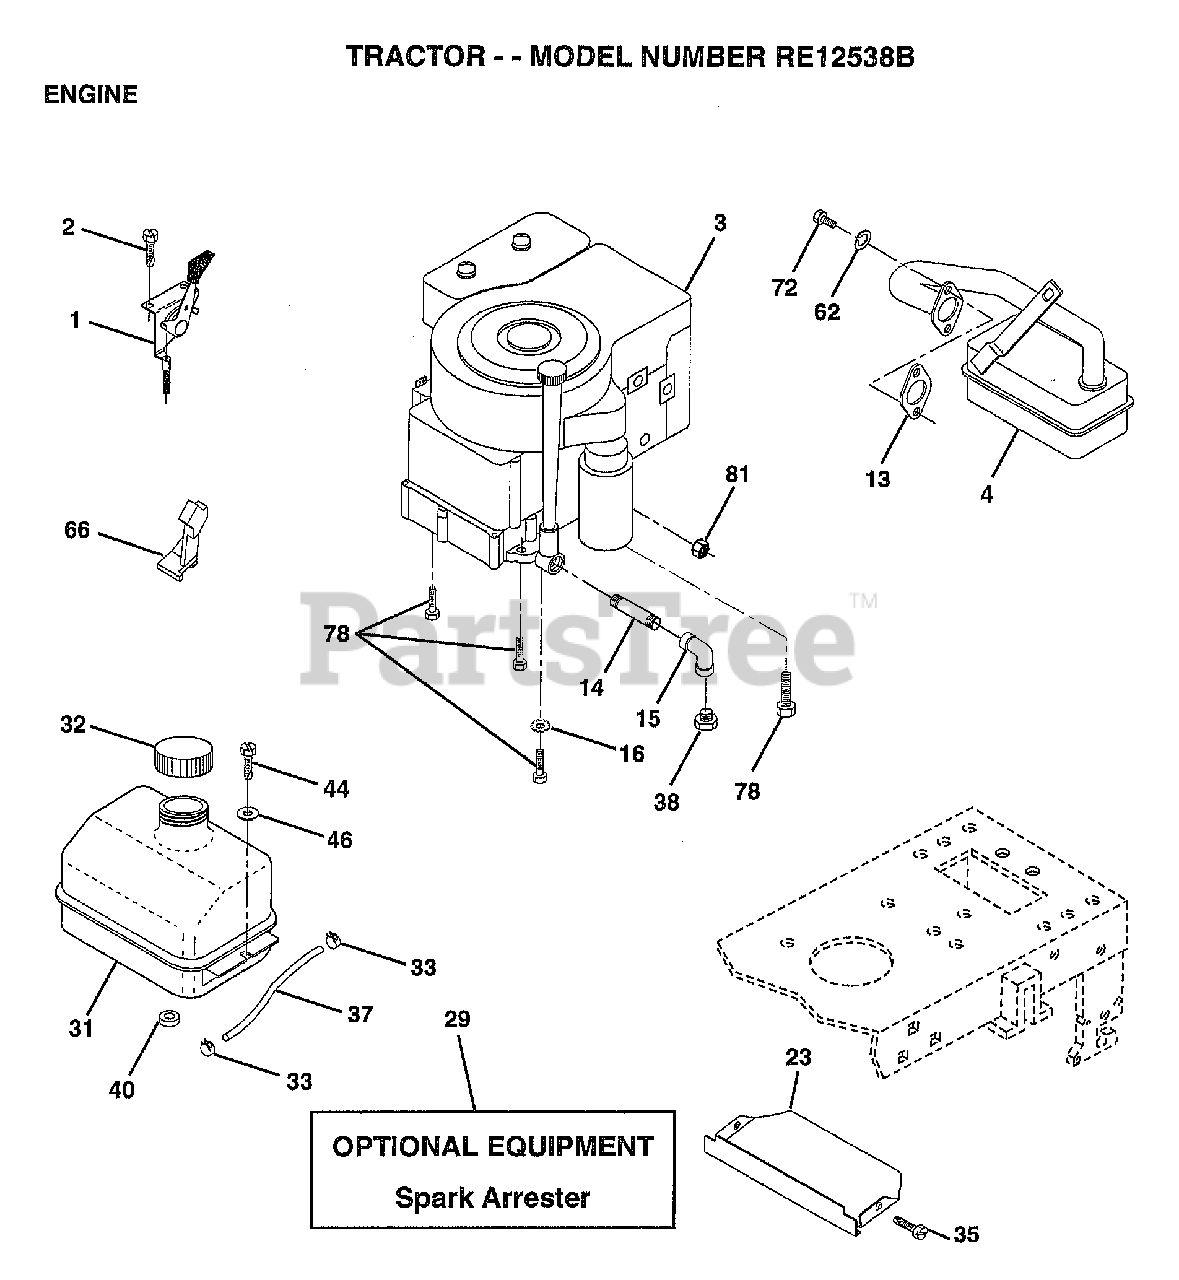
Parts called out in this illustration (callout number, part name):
1	CONTROL.THTL.23.5
2	SCREW LT
4	MUFFLER
13	GASKET ENG 1 313 LD TIN PLATED
14	PIPE NIPPLE
15	ELBOW
16	LOCKWASHER
23	SHIELD.BRN/DBR.GD
31	TANK.FUEL.LT.
32	CAP ASM FUEL
33	HOSE CLAMP
35	SCREW
37	LINE FUEL
44	SCREW HEX CRT
46	WASHER
62	LOCKWASHER
66	"STOP,DASH THROTT"
72	SCREW
78	SCREW
81	NUT
